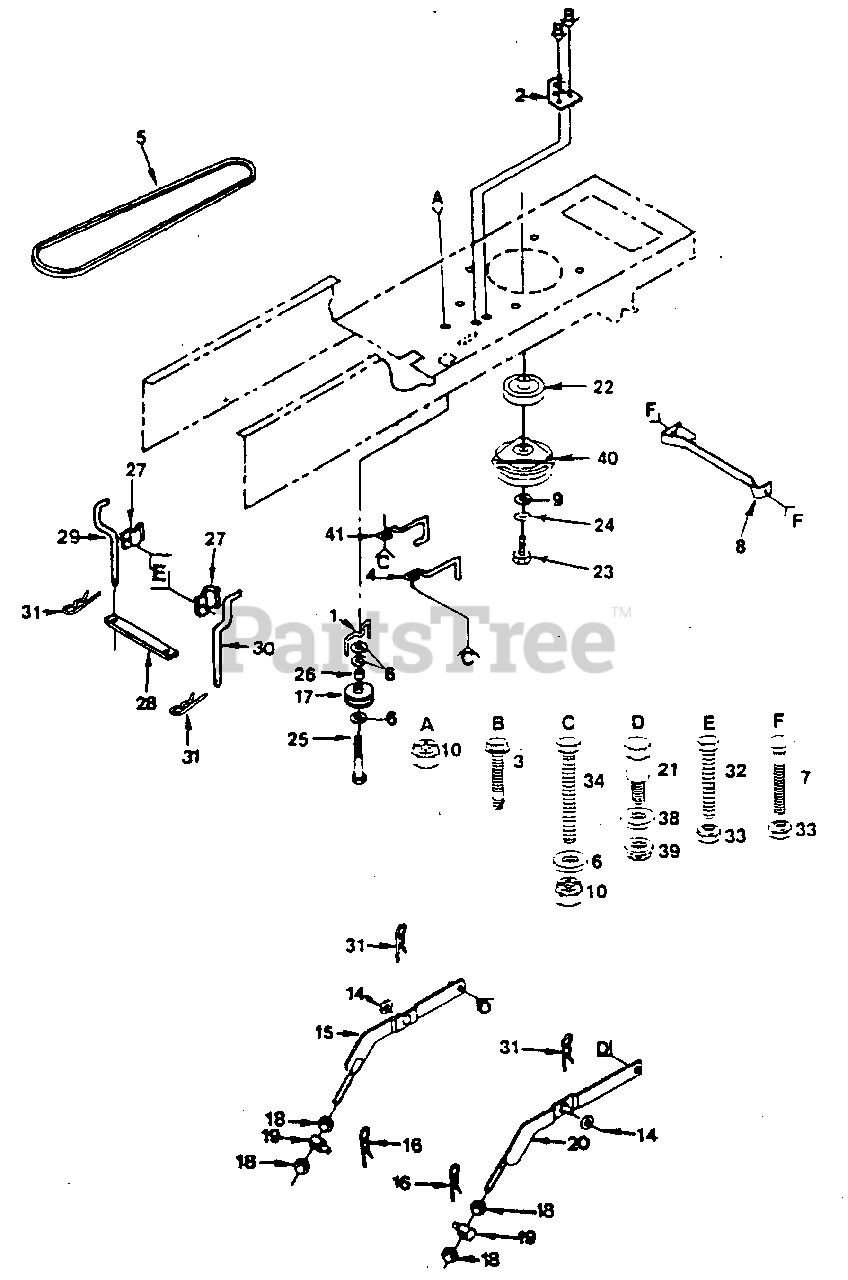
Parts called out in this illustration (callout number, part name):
1	Keeper, Belt (AYP part number)
2	Bracket, Switch (AYP part number)
3	Screw, Hex, Tapping #10-24 x 1/2 (AYP part number)
4	Keeper, Belt, Engine (AYP part number)
5	V-Belt, Drive (AYP part number)
6	Washer 13/32 x 13/16 x 12 Ga. (AYP part number)
7	Bolt, Carriage 5/16-18 x 3/4
8	Retainer, Clutch (AYP part number)
9	Washer 1-1/2 OD x 15/32 ID x .250 (AYP part number)
10	Nut, Crownlock 3/8-16
14	Washer 17/32 x 15/16 x 16 Ga. (AYP part number)
15	Arm Assembly, Suspension, L.H. (AYP part number)
16	Retainer, Spring (AYP part number)
17	Idler, Flat (AYP part number)
18	Nut, Hex 1/2-13 (AYP part number)
19	Trunnion, Lift, Lower (AYP part number)
20	Arm Assembly, Suspension, R.H. (AYP part number)
21	Bolt, Shoulder 3/8-16 (AYP part number)
22	Pulley, Engine (AYP part number)
23	Bolt, Hex Fin 7/16-20 UNF x 4.00 (AYP part number)
24	Washer, Lock (AYP part number)
25	Bolt, Hex 3/8-16 x 2-3/4 (AYP part number)
26	Spacer (AYP part number)
27	Clamp (AYP part number)
28	Strap, Locater (AYP part number)
29	Keeper, Belt, L.H. (AYP part number)
30	Keeper, Belt, R.H. (AYP part number)
31	Spring, Retainer (AYP part number)
32	Bolt, Hex 5/16-18 x 3/4 (AYP part number)
33	Locknut 5/16-18
34	Bolt, Hex 3/8-16 x 1 (AYP part number)
38	Washer, Spring (AYP part number)
39	Locknut, Flange 3/8 (AYP part number)
40	Clutch, Electric (AYP part number)
41	Keeper, Belt, Engine (AYP part number)
